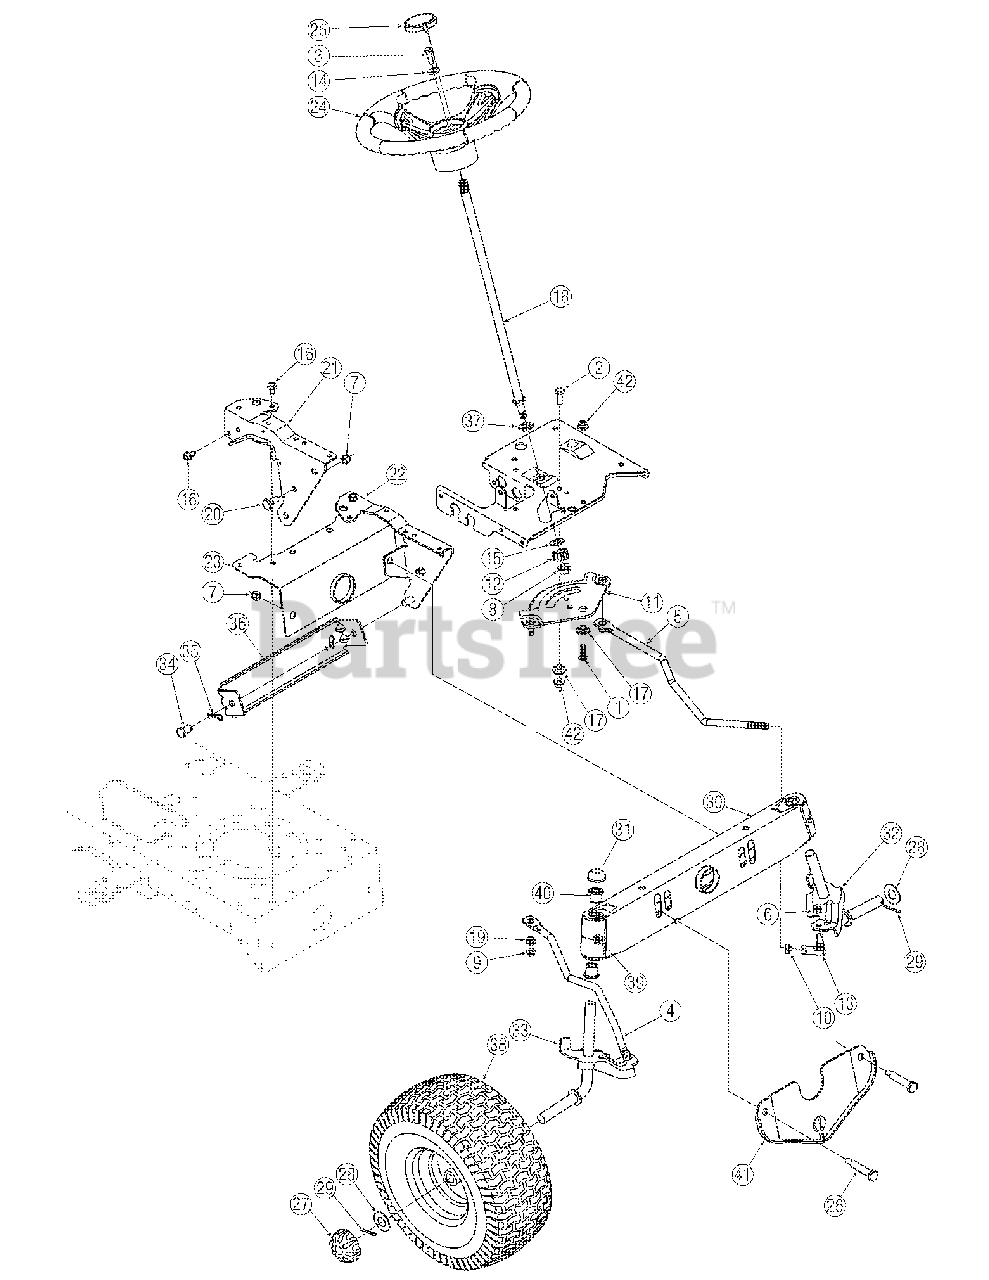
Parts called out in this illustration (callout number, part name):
1	Hex Screw, 3/8-16, 1.00, Gr5
2	Hex Screw, 3/8-16, 1.00, Gr5
3	Hex Screw, 5/16-18, 1.00, Gr5
4	Link, Drag, RH
5	Link, Drag, LH
6	Nut, Hex Lock, 3/8-24
7	Nut, Flange Lock, 3/8-16, Grf
8	Nut, Flange Lock, 7/16-20
9	Nut, Flange Lock, 5/16-18, Gr5
10	Nut, Jam, 7/16-20, Gr2
11	Gear, Steering, 11/90 Ratio
12	Gear, Pinion, Steering
13	Ball Joint, 7/16-20, Lock
14	Washer, Flat, .406 x .875 x
15	Washer, Flat, .51 x 1.12 x .06
16	Screw, 5/16-18, 0.750
17	Spacer, Shoulder, .38 x 1.00 x .31
18	Shaft, Steering, .625 OD x 24.25
19	Plastic Bushing .380 ID
20	Screw, Shoulder, .498 x .340
24	Steering Wheel
25	Steering Wheel Cap, Sprig
25	Steering Wheel Cap, No
26	Shoulder Screw, .5 x 2.380, 3/18-16
26	Shoulder Screw, .5 x 2.2, 3/18-16
27	Deluxe Hub Cap
28	Flat Washer, .78 x 1.589 x .06
29	Cotter Pin, 5/32 x 1.25
30	Cast Iron Pivot Bar
31	Push Cap
32	LH Axle Assembly, .750 (42" Deck)
32	LH Axle Assembly, .750 (46" Deck)
33	RH Axle Assembly, .750 (42" Deck)
33	RH Axle Assembly, .750 (46" Deck)
34	Pin, Clevis, .50 x .78
35	Cotter Pin, Internal, .080 x 1.5625
37	Hex Flange Bearing
39	Pivot Bar End Cap
40	Flange Bearing, .760 x .941 x 1.0
42	Flange Lock Nut, 3/8-16
